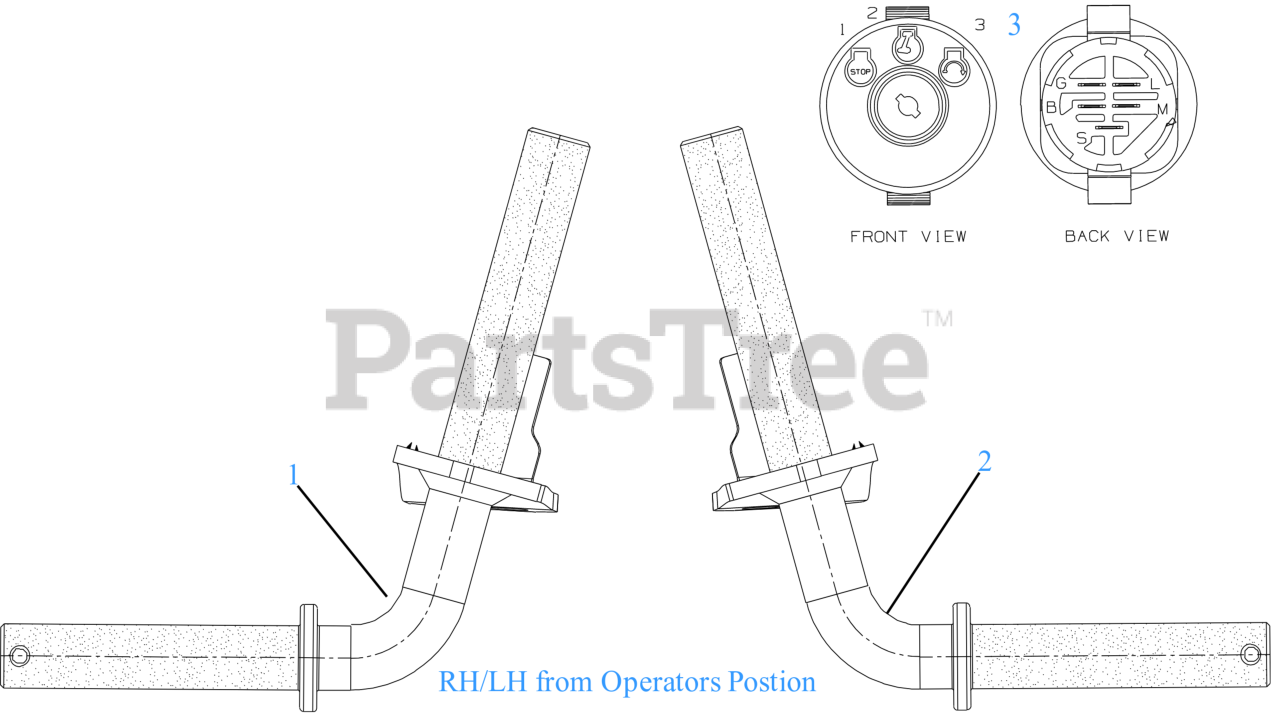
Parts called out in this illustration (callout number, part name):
1	AXLE ASSEMBLY, (RH)
2	FRONT AXLE ASSEMBLY(LH)
3	KEY SWITCH 3 POS WHITE PAD
